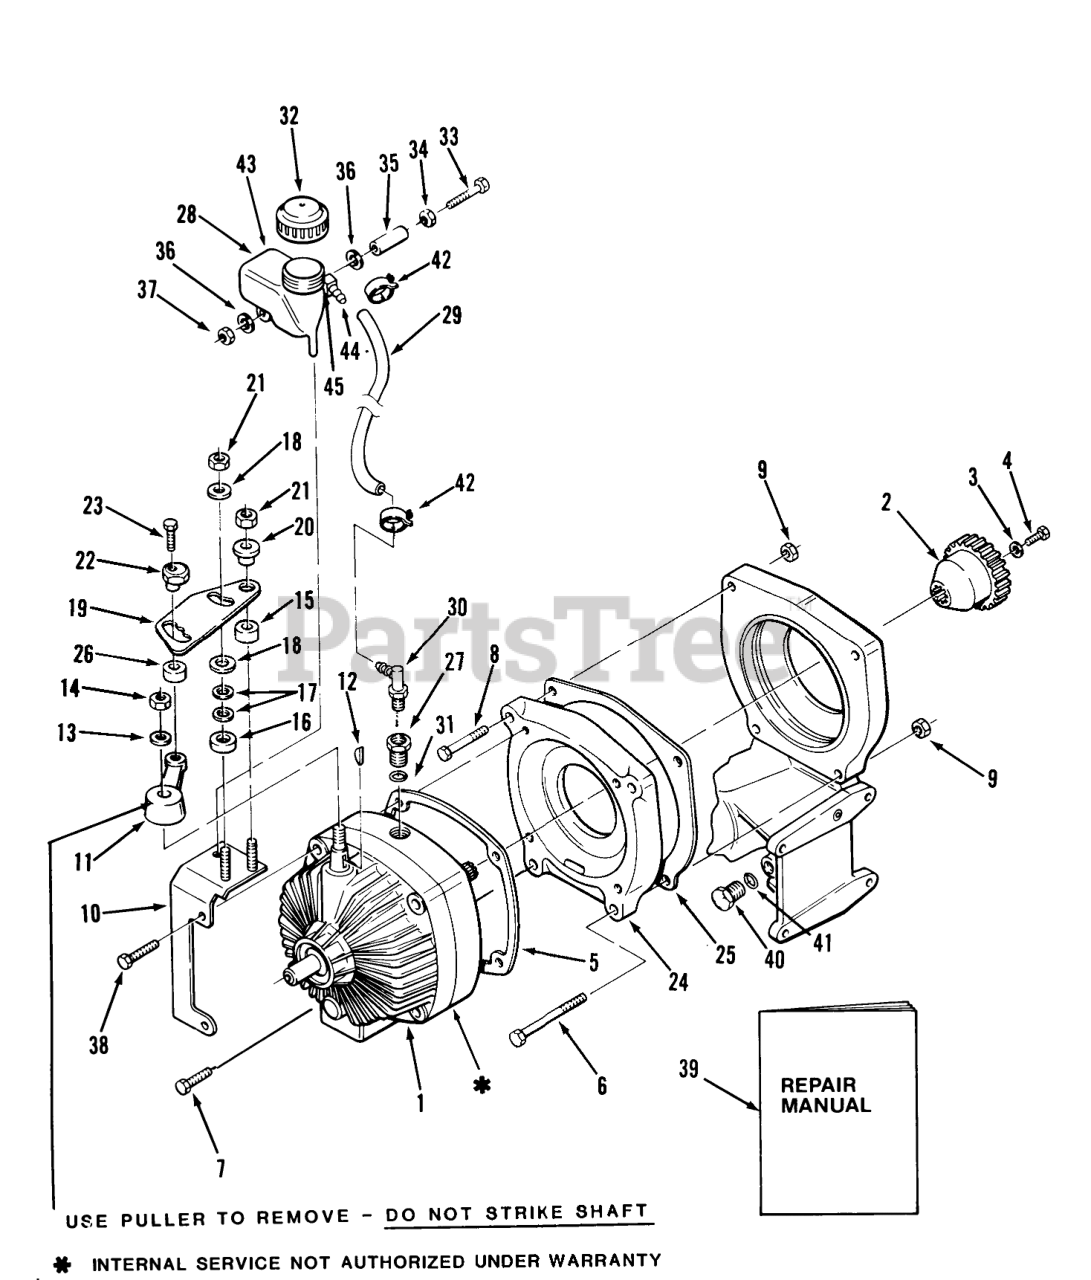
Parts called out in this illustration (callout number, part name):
1	TRANSMISSION HYDRO
2	GEAR 20TEETH DRIVE
3	WASHER
4	H H C S
5	GASKET HYDRO
6	H H C S
7	BLT SH 3/8-16X 1 1/4
8	BOLT SH 3/8-16X3 1/2
9	Nut
10	CONTROL SUPPORT ASSY R
11	ARM SPEED CONTROL
12	KEY WOODR 1/8X1/2 DI
13	Washer
14	NUT
15	SPACER-PIVOT
16	SPACER-FRICTION
17	WASHER-SPRING DISC
18	FRICTION WASHER
19	CAM-SPEED CONTROL (NS)
20	CAM-SPACER
23	Bolt
24	ADAPTER-HYDRO
25	GASKET
26	SPACER CAM
27	Plug Fitting w/O-ring
28	Tank Assembly (Includes elbow & rubber bushing)
29	Hose
30	FITTING-ELBOW
31	0-Ring
32	CAP VENTED B
33	BOLT 1/4-20 X 1 3/4
34	SPEED NUT
35	SPACER
37	Nut
38	Bolt
39	Repair Manual
40	PLUG-WITH O-RING
41	O-ring
42	Clamp
43	Reservoir Tank Only
44	FITTING
45	BUSHING
